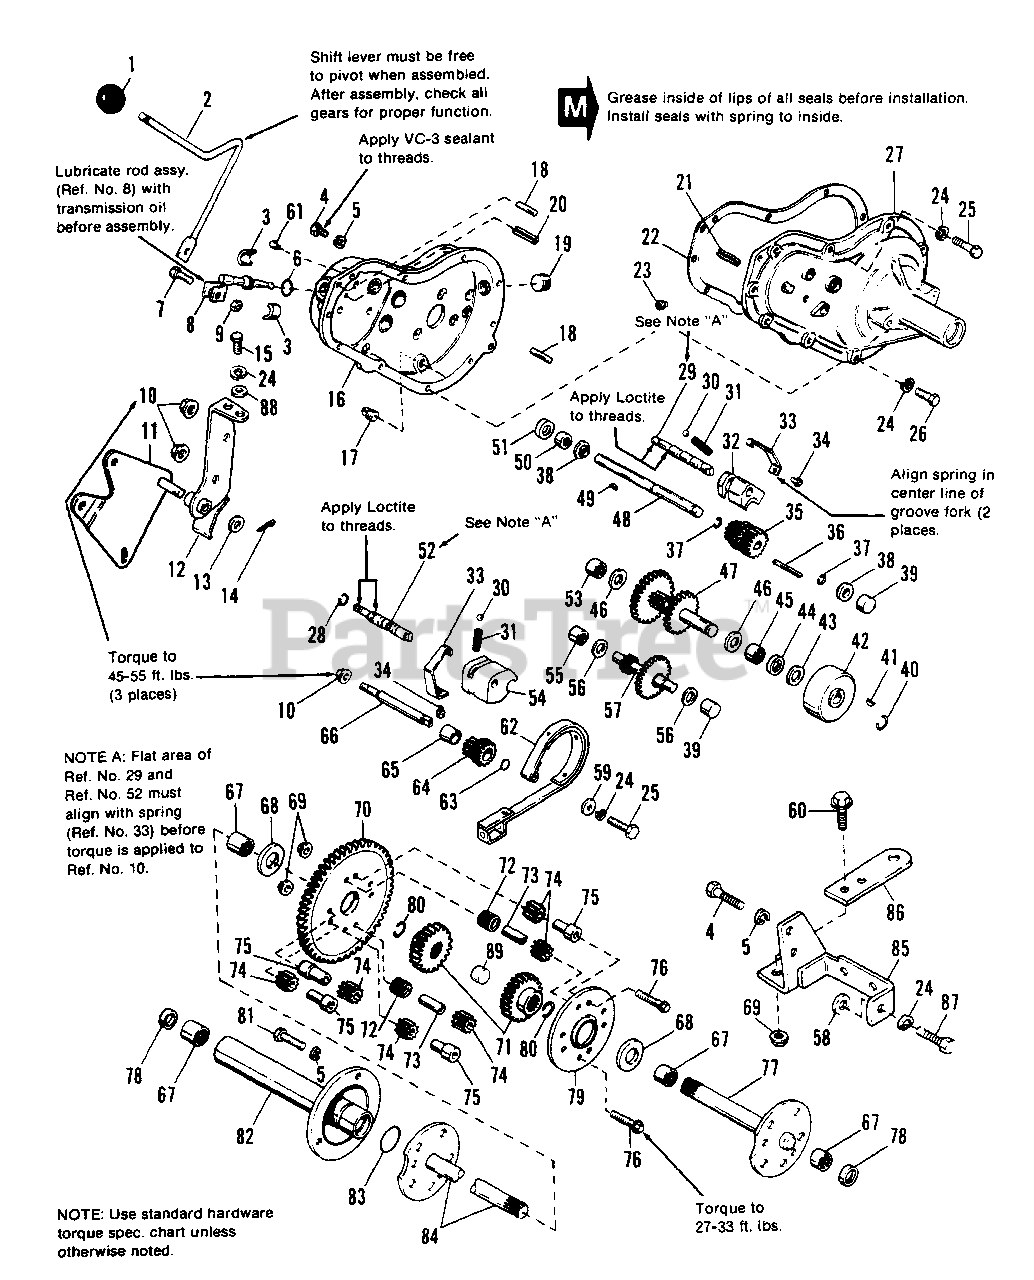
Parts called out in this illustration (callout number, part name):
4	CAPSCREW, Hex, 3/8-18 x 1
5	LOCKWASHER, 3/8
7	CAPSCREW, Hex, 1/4-20 x 1
8	ROD ASSY., Pivot
9	LOCKNUT, Hex, 1/4-20
10	LOCKNUT, Flange, Whizlock, 7/16-14
11	BRACKET ASSY., Pulley
12	SUPPORT ASSY., Transmission
13	WASHER, Plain, 3/8
14	PIN, Cotter, 3/32 x 3/4
15	CAPSCREW, Hex, 5/16-18 x 3/4
16	CASE ASSY., Gear (Incl. Ref. Nos. 3, 6, 8, 18, 20, 50, 53, 55 & 90)
17	PLUG, Pipe, 3/8
18	PIN, Spring, 3/8 Dia. x 1
19	PLUG, Pipe, 3/4
20	PIN ASSY., Roll
21	PIN ASSY., Roll
23	PLUG, Vent
24	LOCKWASHER, 5/16
25	CAPSCREW, Hex, 5/16-18 x 1-1/2
26	CAPSCREW, Hex, 5/16-18 x 1-1/4
27	COVER ASSY., Gear Case (Incl. Ref. Nos. 21, 39, 45 & 67)
28	RING, Retaining
29	SHAFT, Shift, 2nd & 3rd
30	BALL, Shift Lock
32	FORK, Shift, 2nd & 3rd
33	SPRING, Leaf
34	CAPSCREW, Hex, Wash. Hd., 5/16-18 x 5/16
35	PINION ASSY., Drive
37	RING, Retaining
39	BEARING, Roller
40	RING, Snap
41	KEY, Hi Pro, 3/16 x 5/8
42	DRUM ASSY., Brake
43	WASHER, Plain, 25/32
47	PINION SHAFT & GEAR CLUSTER ASSY.
48	SHAFT, Input
49	KEY, 3/16 x 3/4
52	SHAFT, Shift, 1st & Rev.
54	FORK, Shift, 1st & Rev.
57	PINION SHAFT & GEAR ASSY., 1st
58	WASHER, 1/4
59	WASHER, Plain, 5/16
60	CAPSCREW, Hex, Flange, Whiz, 3/8-16 x 1-1/4
61	VENT, Atmospheric
62	BAND, Brake
64	PINION ASSY., 1st & Rev.
66	SHAFT, 1st & Rev. Pinion
67	BEARING, Roller
68	WASHER, Plain, 1
69	LOCKNUT, Flange, 3/8-16
70	GEAR, Drive
71	GEAR, Differential
73	SPACER, Pinion Diff.
74	PINION, Diff.
75	STUD, Diff.
76	CAPSCREW, Special
77	SHAFT, Axle, L.H.
79	PLATE, Diff.
81	CAPSCREW, 3/8-16 x 7/8
82	HOUSING & BEARING ASSY., Axle (Includes Ref. No. 67)
84	SHAFT, Axle, R.H.
85	DRAWBAR ASSY.
87	CAPSCREW, Hex, 5/16 x 1-3/4
88	WASHER, 5/16
